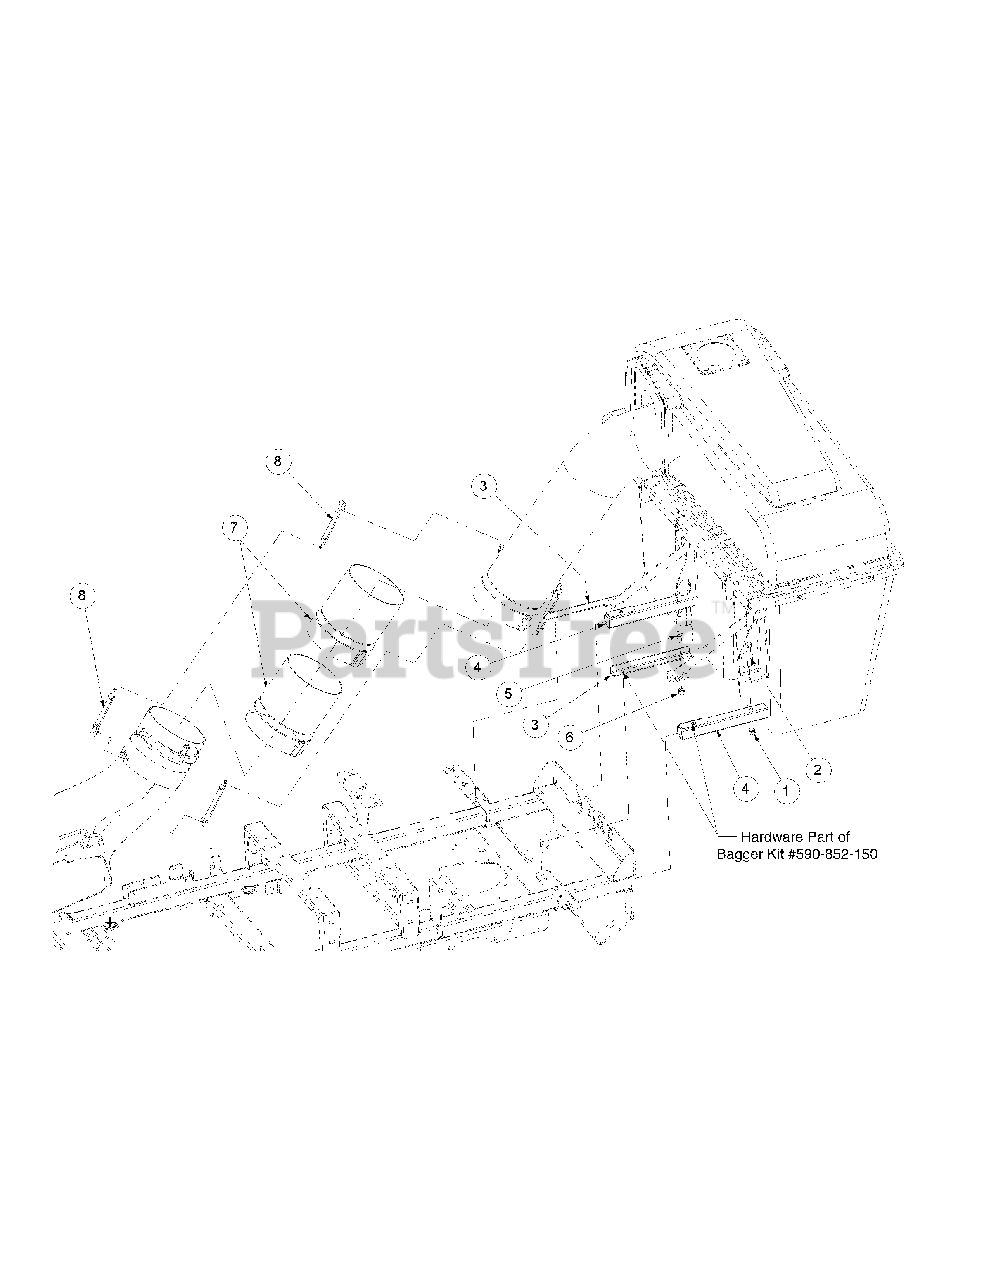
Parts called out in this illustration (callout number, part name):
1	Nut, 1/2-13
2	Hex Cap Screw, 1/2-13 x 3.00
3	Upright Extension Bracket
4	Upright Mount Extension Assembly
5	Hex Cap Screw, 1/2-13 x 1.00
6	Nut, 1/2-13, Hexlock Nylon
7	Extension Tube, 8" Dia. x 10"
8	Retainer Strap
